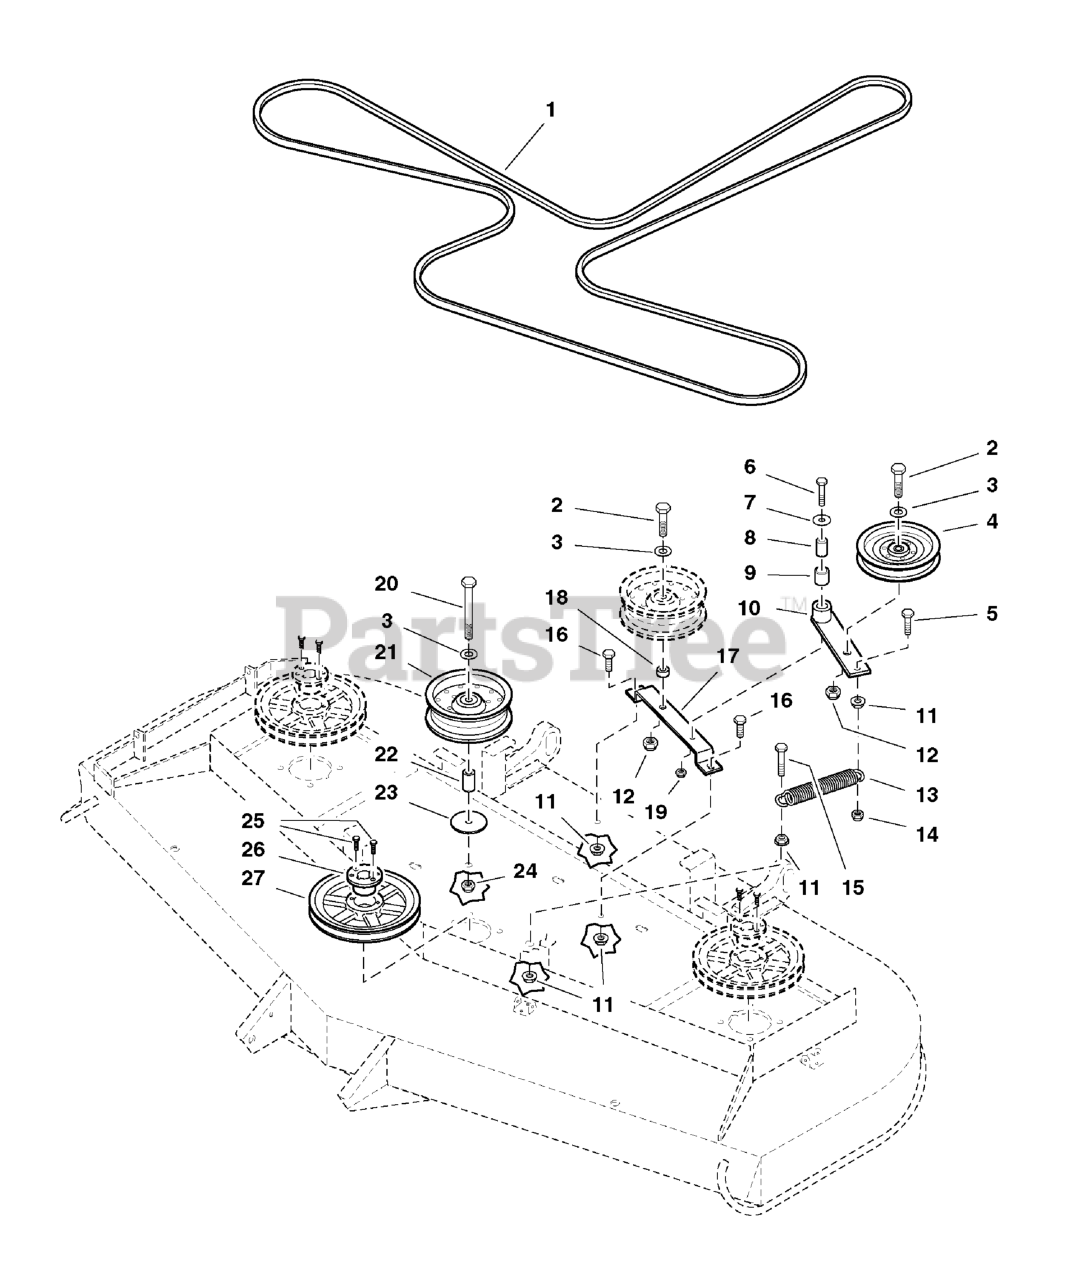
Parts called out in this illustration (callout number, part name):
1	BELT, 5V, 197.90"EL, LRG ARAMID, WRP, RC
2	BOLT, 1/2-20 X 2-1/2" GD5 CZ
3	WASHER, 1/2 SAE
4	IDLER PULLEY
5	BOLT, 3/8-16 X 1-1/2" GD5 CZ
6	BOLT, 5/16-18 x 1-3/4
7	WASHER, 5/16" Fender
8	SPACER, .32 x .75 x 1.06
9	BUSHING, Brass
10	IDLER ARM, Complete
11	NUT, 3/8-16 Hex Serrated Flange
12	NUT, Hex, Nylon Lock, 1/2-20
13	SPRING, Extension
14	NUT, 3/8-16 HEX NYLON LOCK
15	BOLT, 3/8-16 X 2, GD5, CZ
16	BOLT, 3/8-16 X 1" GD5 CZ
17	IDLER MOUNT
18	SPACER, .52 x 1.00 x .56
19	NUT, 5/16-18 Hex Nylon Lock
20	BOLT, 1/2-13 x 4-1/2
21	PULLEY, Idler
22	SPACER, .52 X 1.00 X 1.81
23	WASHER, Chain
24	NUT, 1/2-13 HEX NYLON LOCK
25	BOLT, 1/4-20 X 1" GD5 CZ
26	BUSHING, Tapered Hub
27	PULLEY, Spindle
